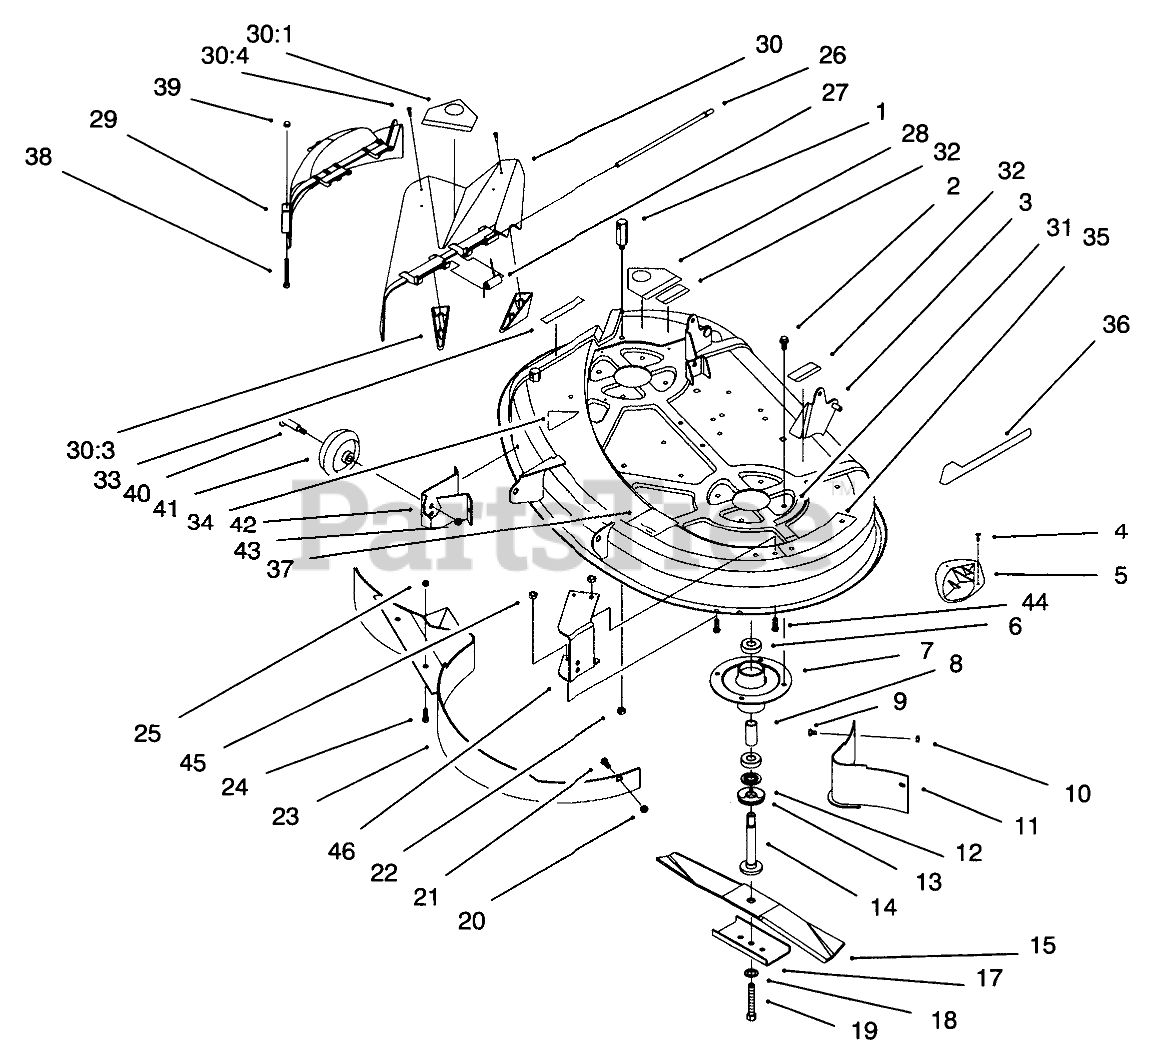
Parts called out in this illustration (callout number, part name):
1	REAR PIVOT POST (PLTD)
2	SCREW-TAPTITE
3	Deck Wa-38"
4	Screw-PPH #8 X .62 (Only On: 71193)
5	Plate-Kicker (Only On: 71193)
6	BEARING-BALL
7	HOUSING-SPINDLE
8	SPACER
9	Screw-HH (Only On: 71193)
10	Nut-Lock (Only On: 71193)
11	Wa-Baffle (Only On: 71193)
12	SPACER
13	SHIELD-BEARING
14	SHAFT-SPINDLE
15	Blade-19.32" (Only On: 71217)
15	Blade-19.32 Recycler (Only On: 71193)
17	Stiffener-Blade (Only On: 71193)
18	WASHER-BELLEVILLE
19	SCREW-HH
20	Nut-Lock (Only On: 71193)
21	Screw-CARR (Only On 71193)
22	NUT-LOCK, NI
23	Wa-Baffle (Only On: 71193)
24	Screw-HH (Only On: 71193)
25	Nut-Lock (Only On: 71193)
26	ROD-HINGE DEFLECTOR
27	SPRING
28	Decal-Danger (Only On: 71193)
28	Decal-Danger (Only On: 71217)
29	Recycler Cover ASM (Only On: 71193)
30	ASM-Deflector (Only On: 71193) (Incl. Ref. #30:1)
30	ASM.-38" Deflector (Only On: 71217) (Incl. Ref. #30:1 & 30:3-30:4)
30:1	Decal Danger (Only On: 71193)
30:1	Decal Danger (Only On: 71217)
30:3	Kicker-CE (Only On: 71217)
30:4	Screw-Phillips Pan Head (Only On: 71217)
31	Decal-Shield Danger (Only On: 71193)
31	Decal-Shield Danger (Only On: 71217)
32	Decal-Warning (Only On: 71193)
32	Decal-Warninig (Only On: 71217)
33	Decal-Danger (Only On: 71193)
33	Decal-Deflector Danger (Only On: 71217)
35	Decal-Danger (Only On: 71193)
36	Decal-Deck (Only On: 71193)
37	DECAL-ROUTING, BELT
38	Screw-HH (Only On: 71193)
39	Nut-Cap (Only On: 71193)
40	Wheel Bolt (Only On: 71217)
41	Wheel-Deck (Only On: 71217)
42	Bracket-Deck Wheel RH (Only On: 71217)
43	Nut-Lock (Only On: 71217)
44	Screw-HH (Only On: 71217)
45	Nut-Lock (Only On: 71217)
46	Bracket-Deck Wheel LH (Only On: 71217)
